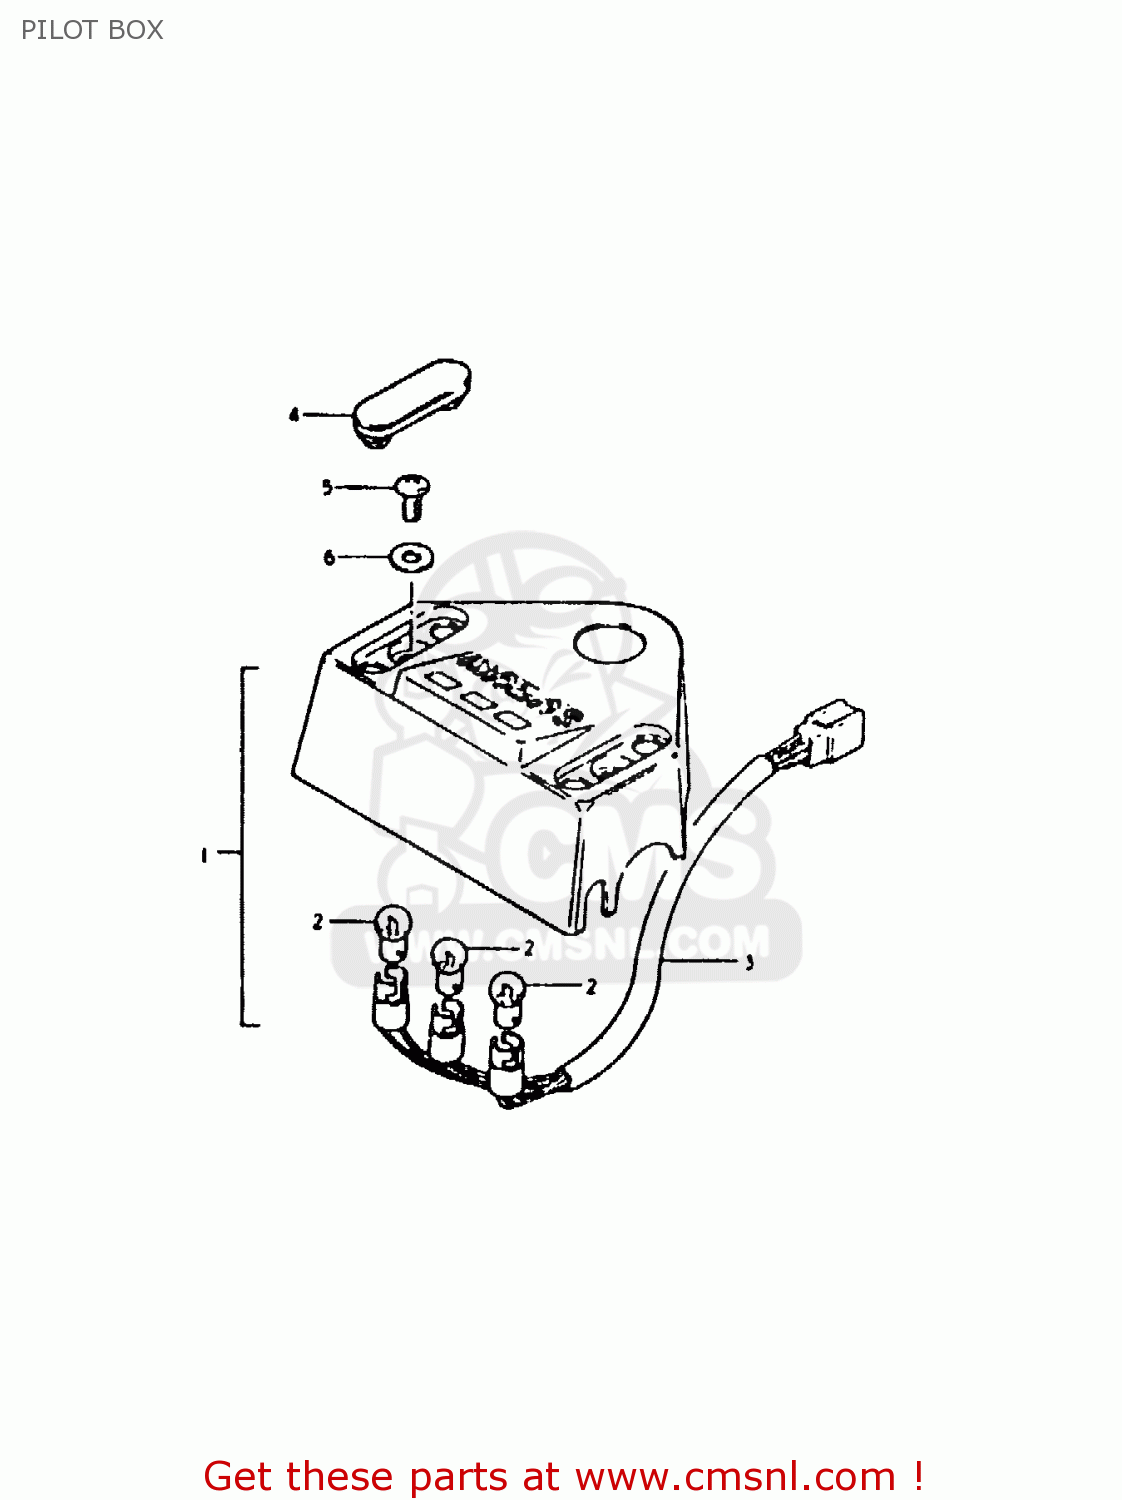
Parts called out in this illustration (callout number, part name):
1	PILOT BOX ASSY
2	BULB(6V/3W)
3	SOCKET
4	CAP,PILOT LAMP BOLT
5	SCREW 6X12
6	WASHER
